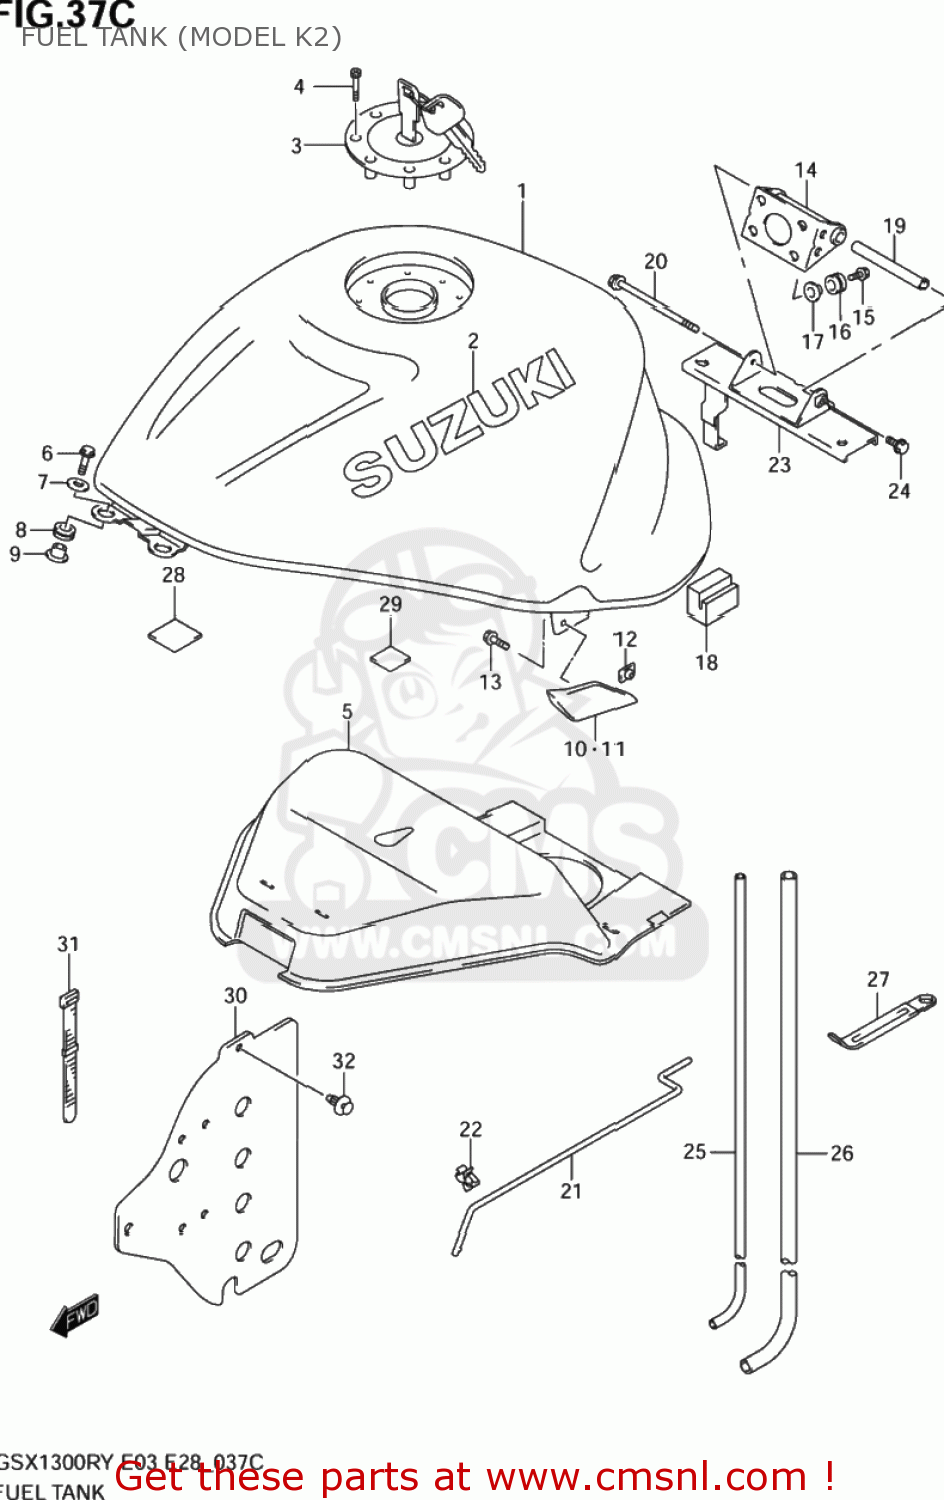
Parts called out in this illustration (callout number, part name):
1	TANK ASSY,FUEL
2	EMBLEM,FUEL TANK
3	CAP SET,FUEL TANK
4	BOLT(5X20)
5	SHIELD,FUEL TANK HEAT
6	SCREW(6X25)
7	WASHER(6.5X18X1.5)
8	CUSHION
9	WASHER
10	COVER,FUEL TANK SIDE,R
11	COVER,FUEL TANK SIDE,L
12	PLATE,FUEL TANK SIDE
13	SCREW 6X10
14	BRACKET COMP,FUEL TANK
15	BOLT(6X20)
16	CUSHION
17	WASHER
18	CUSHION,FUEL TANK SIDE
19	SPACER,FUEL TANK RR
20	BOLT
21	STAY,FUEL TANK
22	CLAMP
23	BRACKET,FUEL TANK RR NO.2
24	BOLT
25	HOSE,FUELTANK BREATHER
26	HOSE(7X11X600)
27	CLAMP(L:65)
28	CUSHION
29	CUSHION,FUEL TANK COVER
30	SHEET,HEAT SHIELD RUBBER
31	CLAMP(L:165)
32	CLIP(BLACK)
